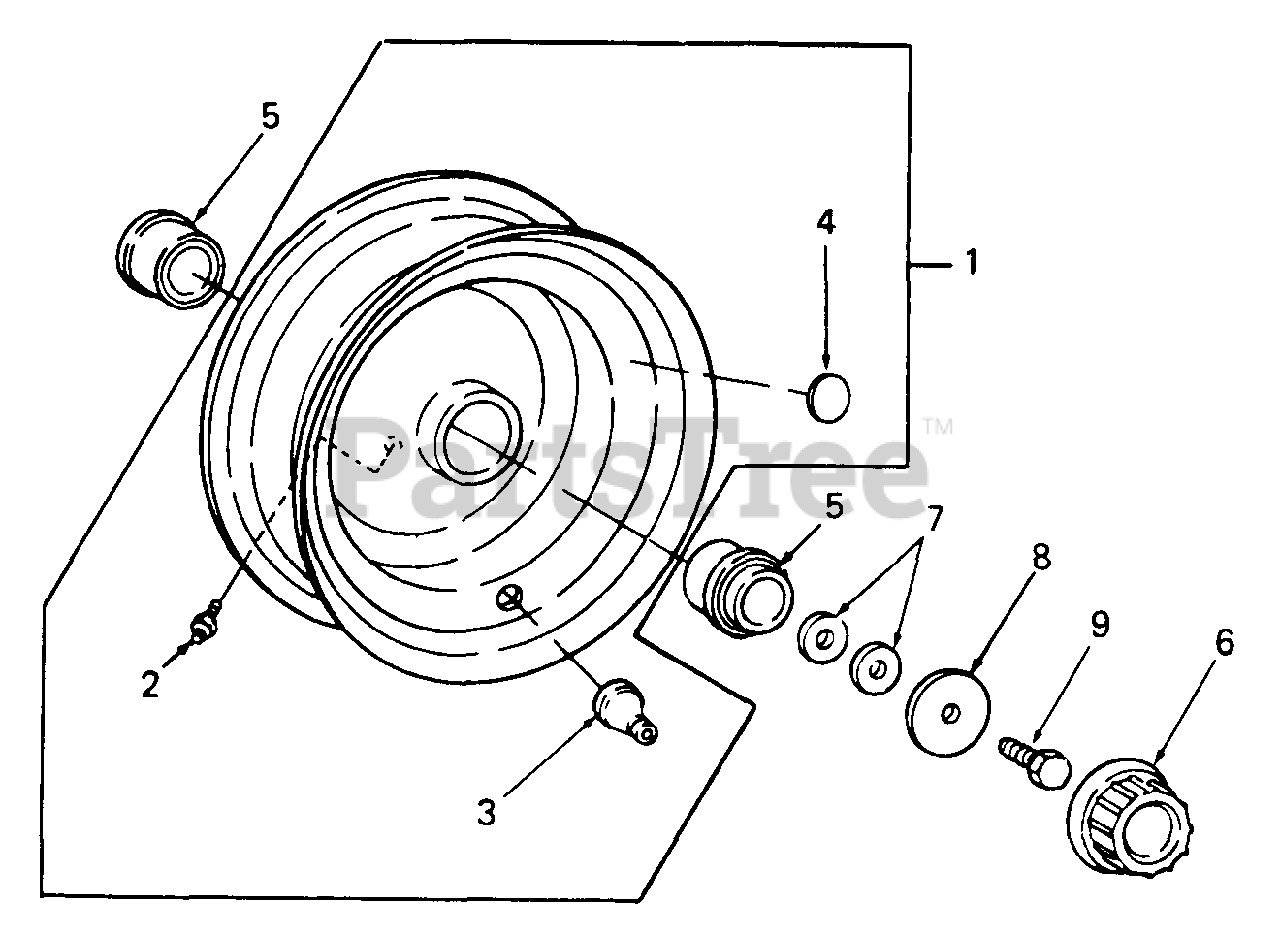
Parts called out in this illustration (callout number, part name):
1	Wheel Assy, Front
2	Fitting, Lube
3	Valve, Tubeless Air
4	Label, Inflation
5	Bearing, Wheel Ball
6	Cap, Hub
7	Washer, Flat, .531 x 1.25 x .100 Thk
8	Washer, Flat, .535 x 1.92 x .060 Thk
9	Bolt, Patch, 1/2-13 x 1.0 Lg GR5
